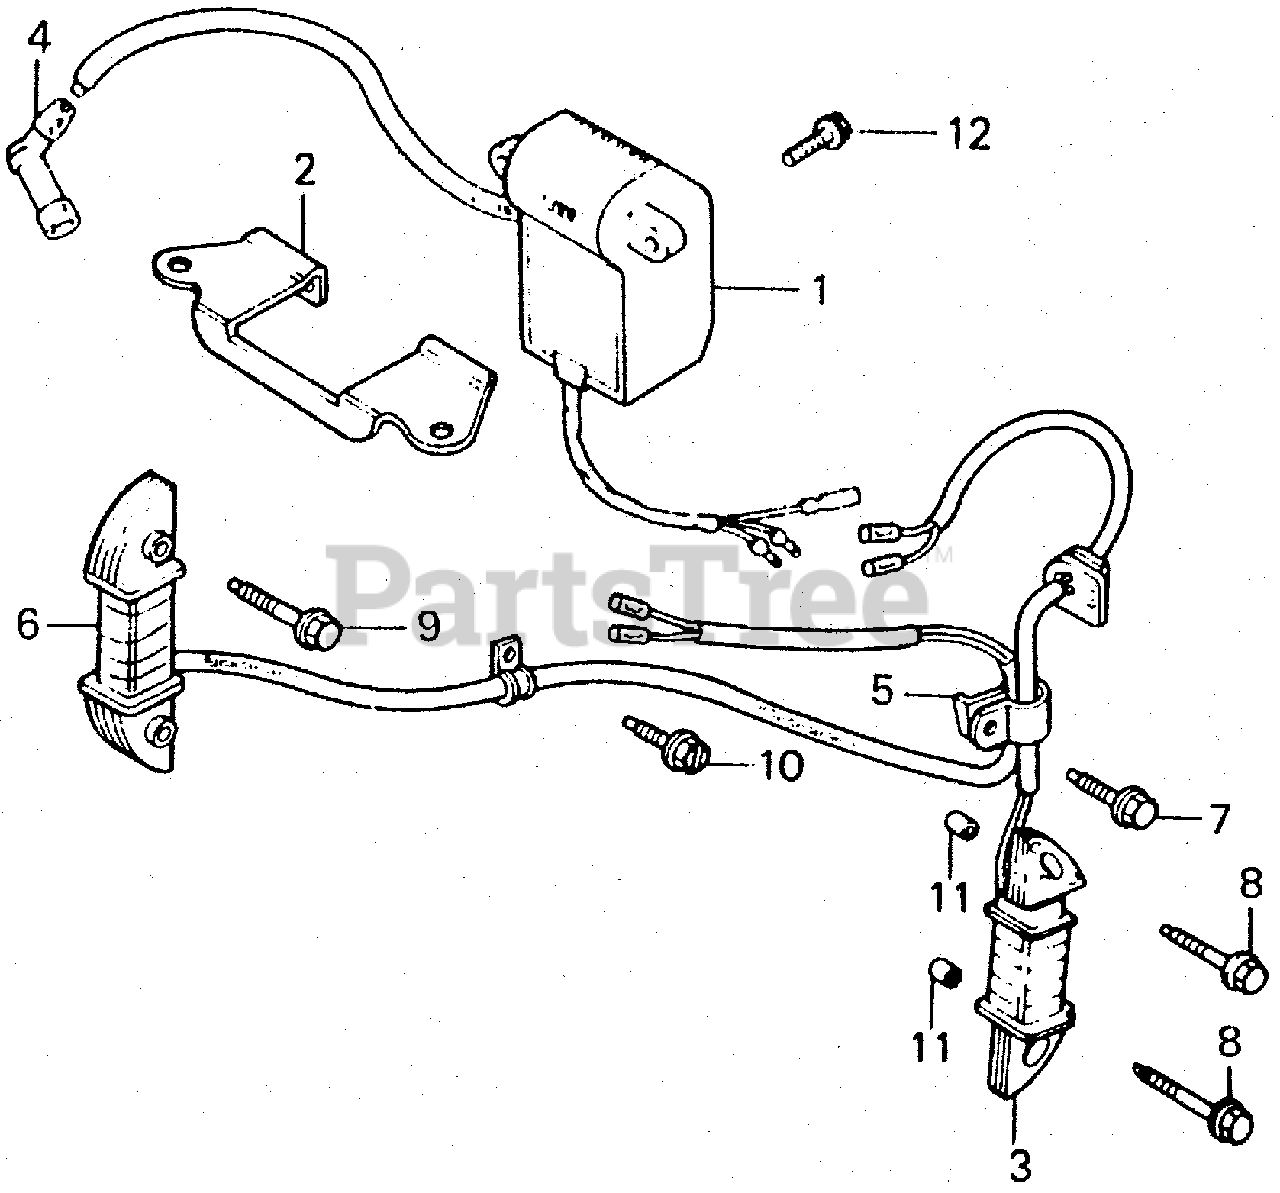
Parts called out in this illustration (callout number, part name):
1	MODULE, IGNITION CONTROL (CDI)
2	STAY, IGNITION CONTROL MODULE
3	COIL ASSY., EXCITER
4	CAP ASSY., NOISE SUPPRESSOR
5	CLAMP, IGNITION WIRE
7	BOLT, FLANGE (6X12) (CT200)
8	BOLT, FLANGE (6X28)
11	PIN, DOWEL (8X14)
12	BOLT, FLANGE (6X12)
